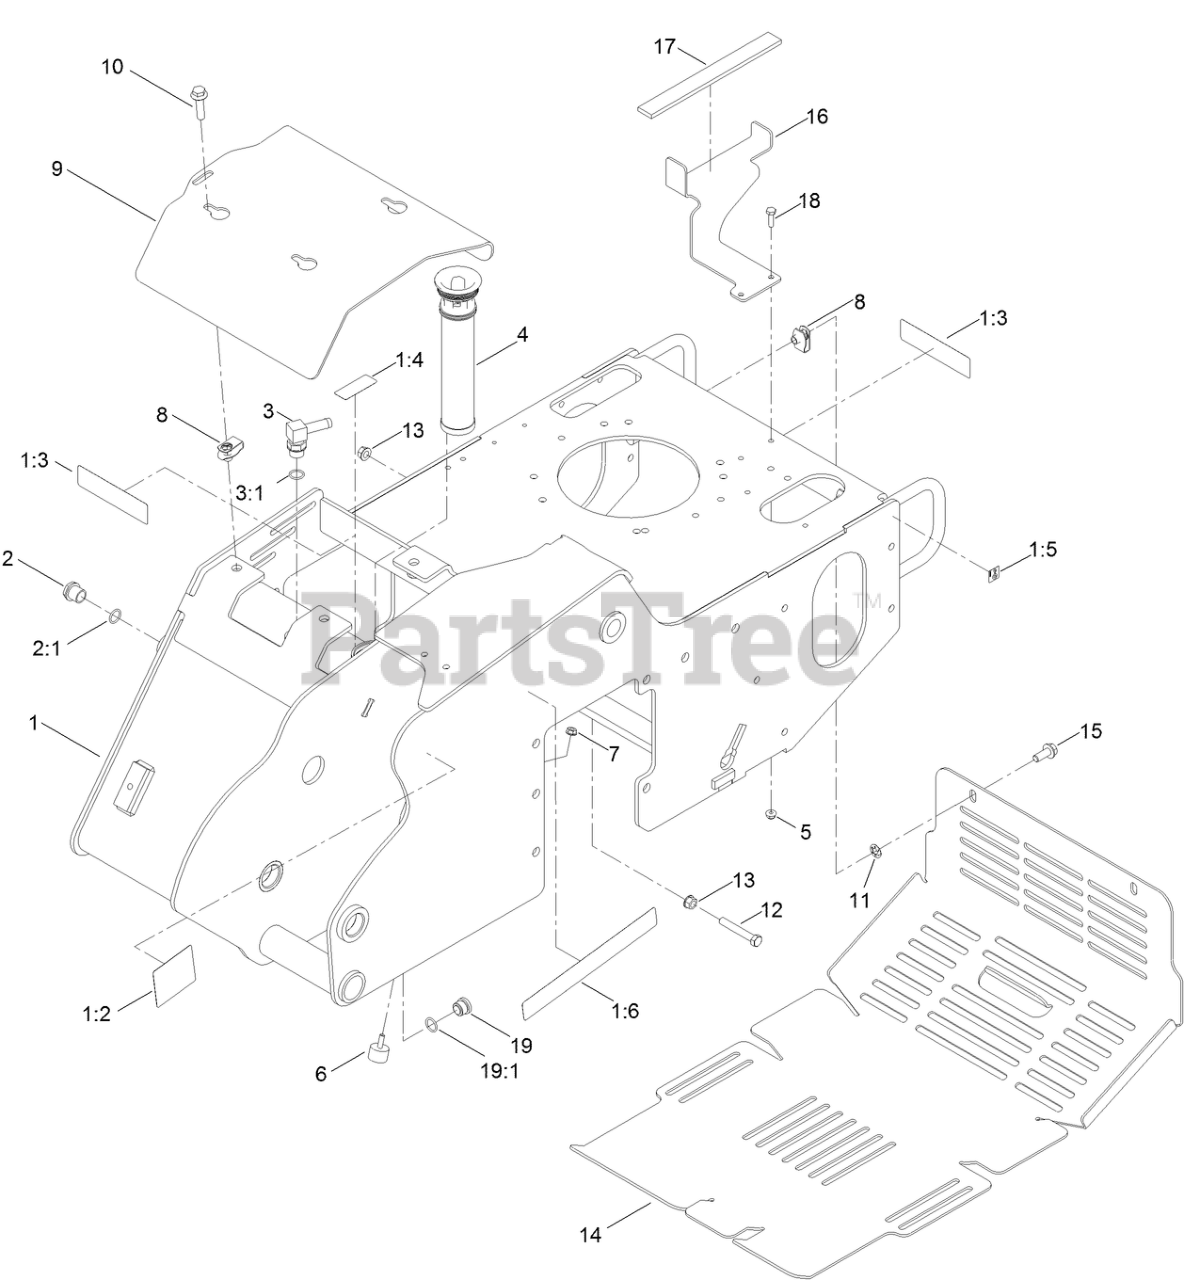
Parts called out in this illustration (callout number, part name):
1	MAIN FRAME ASM
1:2	DECAL-WARNING
1:3	DECAL-DANGER
1:4	DECAL-OIL, HYD
1:5	DECAL-POINT, LIFT
1:6	DECAL-INTELLITRENCH
2	SIGHT GLASS ASM
2:1	O-RING
3	FITTING-ELBOW, 90
3:1	O-RING
4	IN-TANK FILTER ASM
5	NUT-HF
6	BUMPER
7	NUT-HF
8	NUT-CLIP, U
9	PLATE-COVER, FRONT
10	SCREW-HHF
11	NUT-PUSH
12	SCREW-HH
13	NUT-FLANGE
14	COVER-REAR
15	SCREW-HHF
16	BRACKET-TANK
17	PAD-FOAM
18	SCREW-HH
19	PLUG ASM
19:1	O-RING
